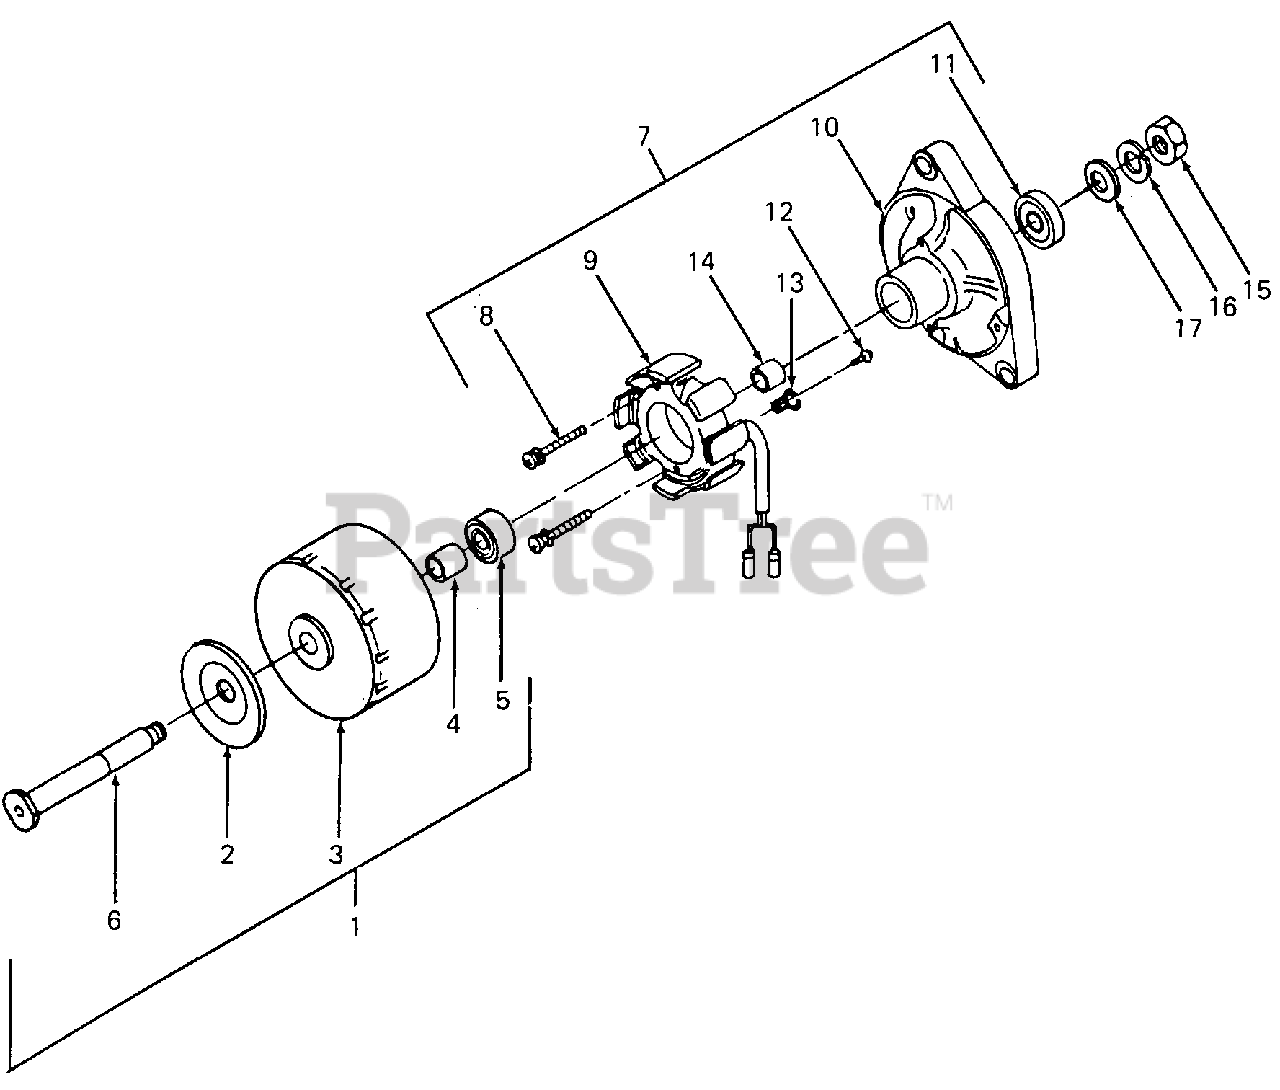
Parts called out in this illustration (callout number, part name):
1	Rotor Complete
5	Bearing, Ball
7	Stater Complete
8	Screw, Round Head
11	Bearing, Ball
12	Screw, Round Head
16	Washer, Spring
